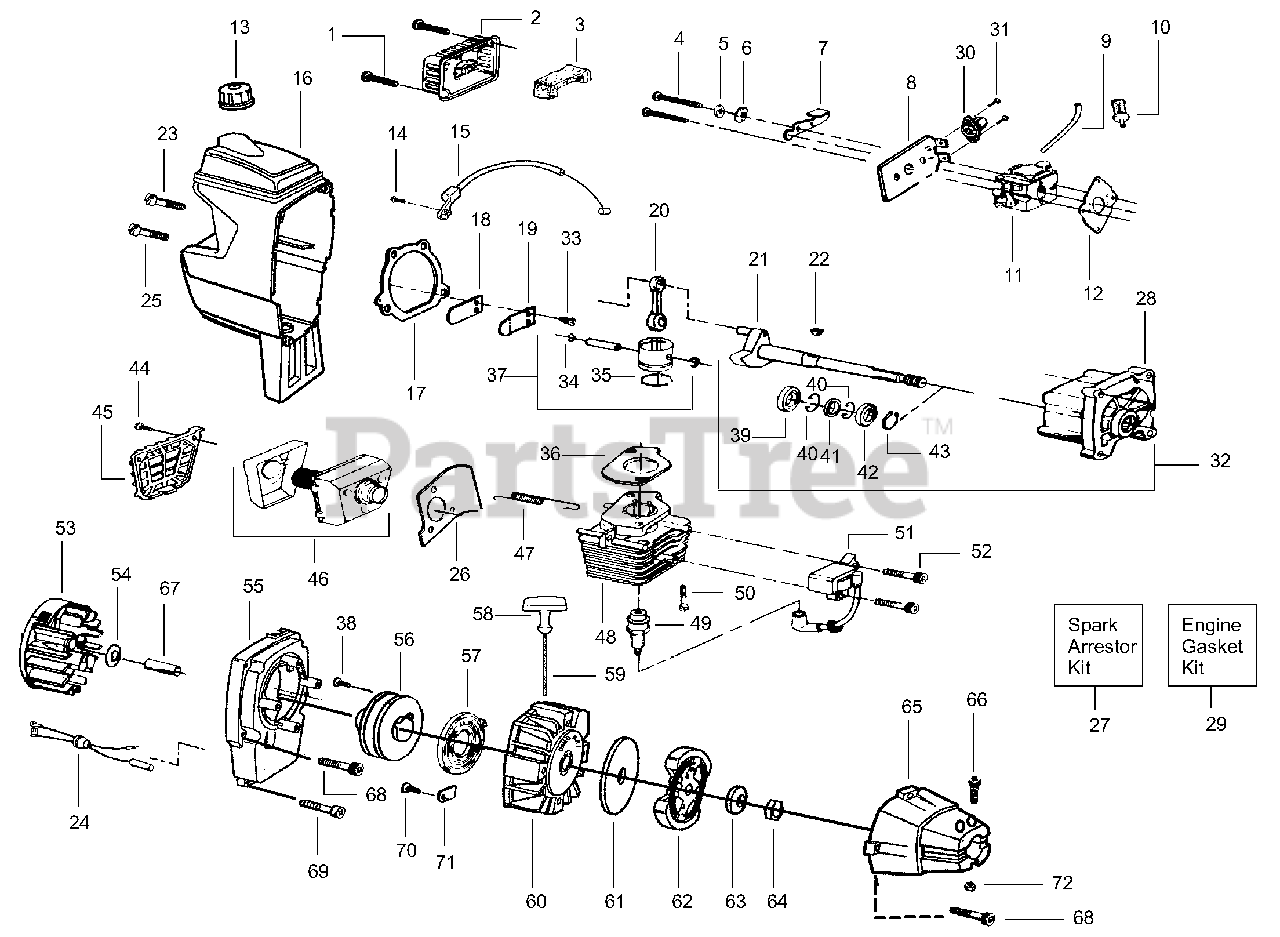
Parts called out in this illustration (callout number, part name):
2	Air Filter Cover
3	Air Filter
5	Choke Spacer
7	Choke Shutter
8	Air Filter Plate
9	Fuel Line Kit
10	Fuel Pick-up Ass'y.
11	Carburetor Ass'y. Kit
12	Gasket-Carburetor
13	Fuel Cap Ass'y.
15	Throttle Cable Ass'y.
16	Shroud/Tank Ass'y.
17	Gasket-C'case/Shroud
18	Reed Valve
19	Reed Stop
20	Connecting Rod Ass'y.
21	Crankshaft Ass'y.
22	Flywheel Key
24	Leadwire/Grommet Ass'y.
26	Heat Shield/Air Dam
27	Spark Arrestor Kit
28	Crankcase Ass'y.
29	Engine Gasket Kit
30	Bulb Ass'y.
32	Crankcase/Crankshaft Ass'y.
34	Piston Pin Retainer
35	Piston Ring
36	Gasket-Cylinder
37	Piston Kit
39	Inner Bearing
40	Retaining Ring
41	Crankshaft Seal
42	Outer Bearing
43	Retaining Ring-C'shaft
45	Muffler Guard
46	Muffler Kit
47	Muffler Spring
48	Cylinder Kit
49	Spark Plug (RCJ-8Y)
51	Ignition Module
53	Flywheel Ass'y.
55	Fan Housing
56	Starter Pulley Kit
57	Starter Spring
58	Starter Handle
59	Rope Kit
60	Pulley Housing Ass'y.
61	Washer-Clutch
62	Clutch Ass'y. Kit
63	Washer-Bevel
65	Clutch Housing
67	Spacer-Clutch
71	Retainer
